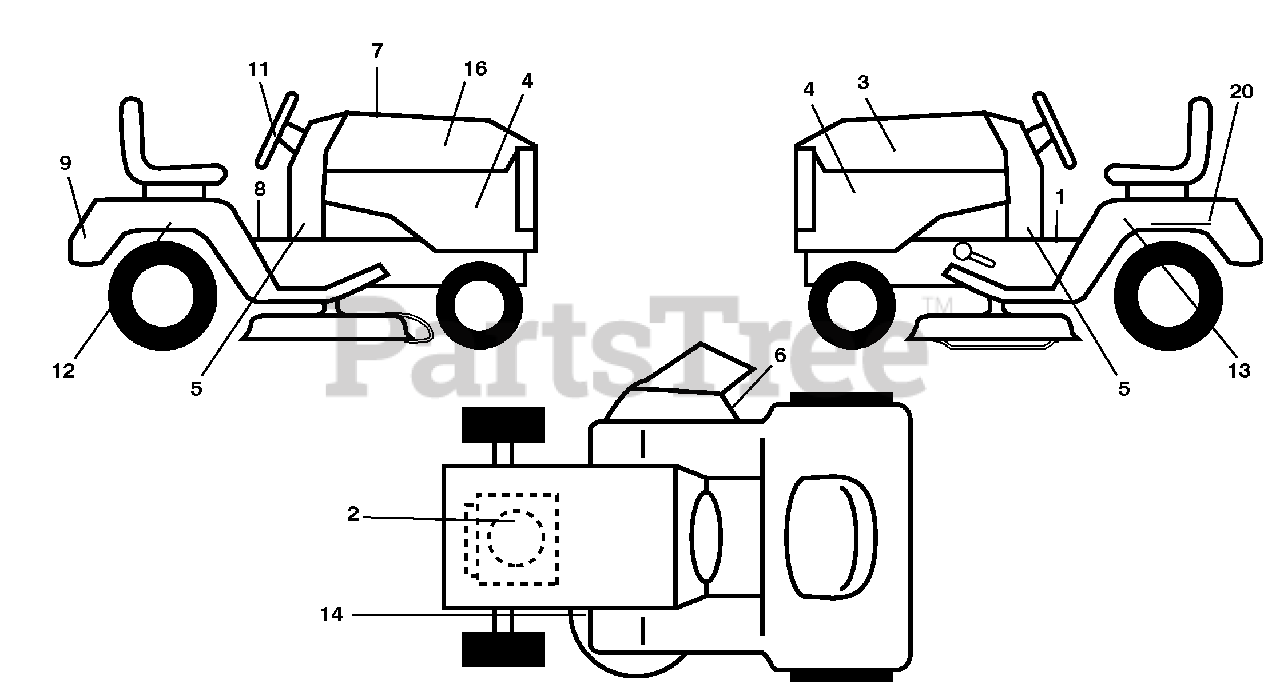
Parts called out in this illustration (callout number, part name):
2	Decal Eng. H.P.
3	Decal Hood LH
4	Decal Side Panel Logo
5	Decal Lwr Dash
6	Decal Warning, Keep Hand Away
7	Decal Replacement Parts
8	Decal Fender Warn S/F
9	Decal Fender Logo
11	Decal Ins Strg Whl
12	Decal Fend SD RH
13	Decal Fend SD LH
14	Decal V-Belt Schematic
16	Decal Hood RH
20	Decal Bat Dan/Psn
20	Pad Footrest LH
20	Pad Footrest RH
20	Manual Operator's (Eng)
20	Manual Operator's (French)
